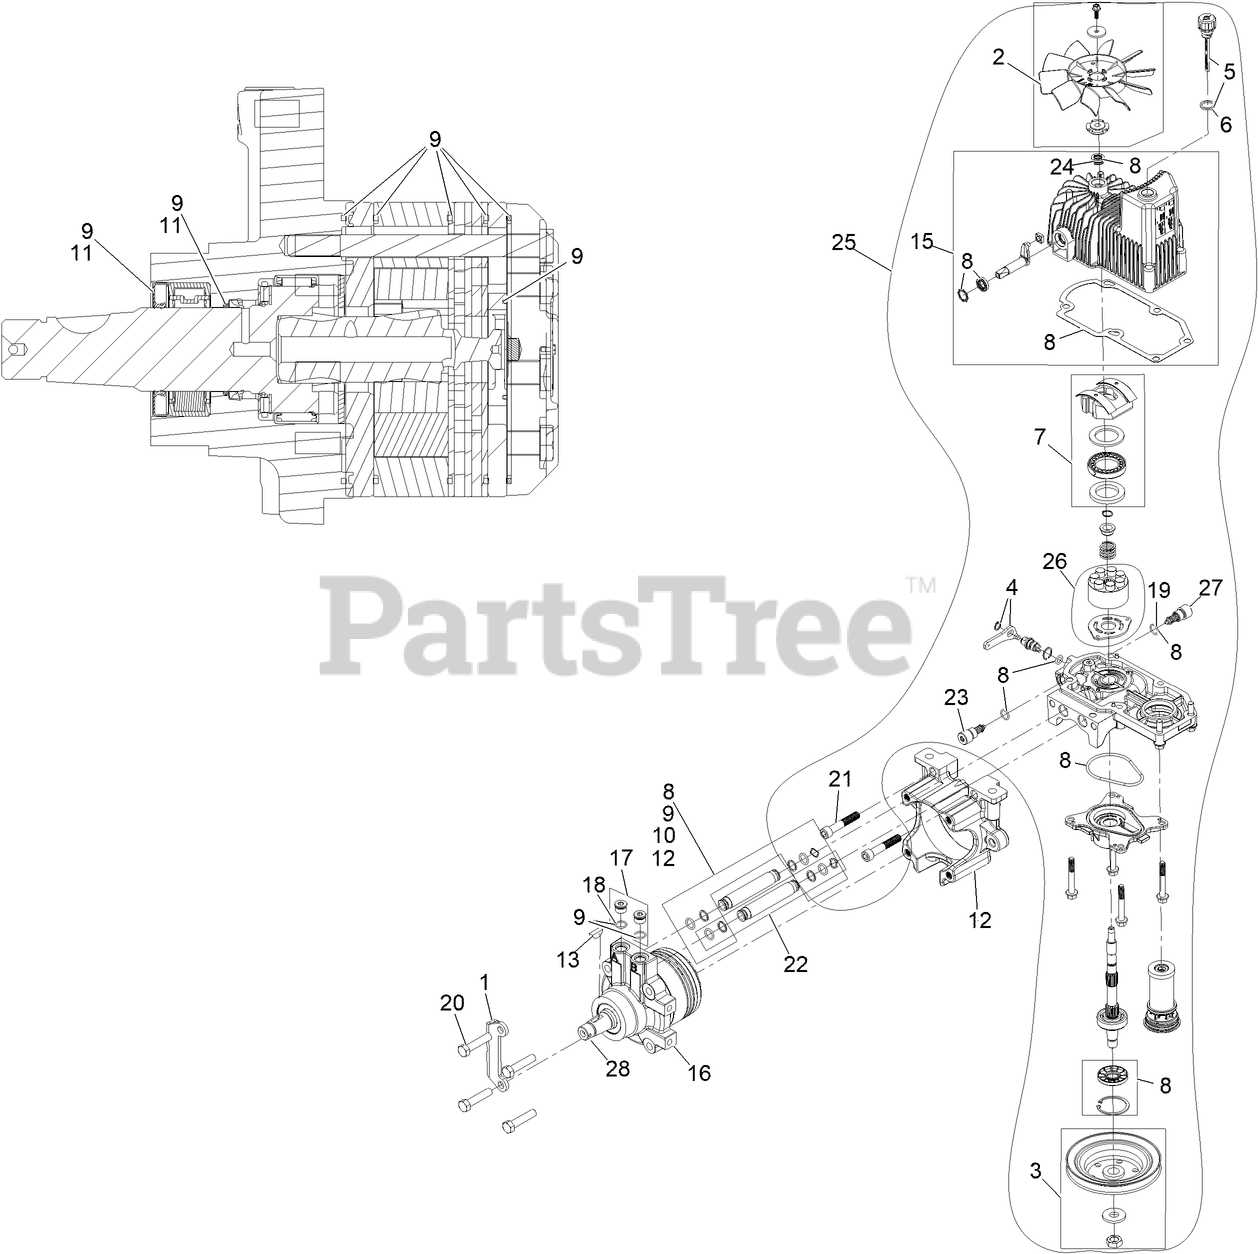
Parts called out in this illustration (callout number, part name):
1	MOUNT-SHOE, HORSE
2	FAN KIT
3	PULLEY KIT
4	HANDLE-BYPASS VALVE, HYDRO
5	DIPSTICK-HYDRO W/GASKET
6	GASKET-DIPSTICK, HYDRO
7	SWASH BLOCK KIT
8	PUMP SEAL KIT
9	MOTOR SEAL KIT
10	TUBE SEAL KIT
11	OUTPUT SHAFT SEAL KIT
12	NOSE CUP-UHT
13	KEY-WOODRUFF
15	HOUSING-HYDRO, RH
16	MOTOR-HYDRAULIC, RH 280CC
17	MAGNETIC PLUGS SERVICE KIT
18	O-RING
19	O-RING-CHECK VALVE
20	SCREW HH
21	SCREW-HSH
22	HYDRAULIC TUBE KIT
23	SHOCK VALVE, 16CC HYDRO
24	SEAL-FAN DRIVE
25	KIT, PUMP SECTION 16CC RH
26	KIT, ROTATING GRP 16CC RH
27	SHOCK VALVE ORIFICED 3300
28	OUTPUT SHAFT- TL UHT MOTOR
99	PULLER-PULLEY
